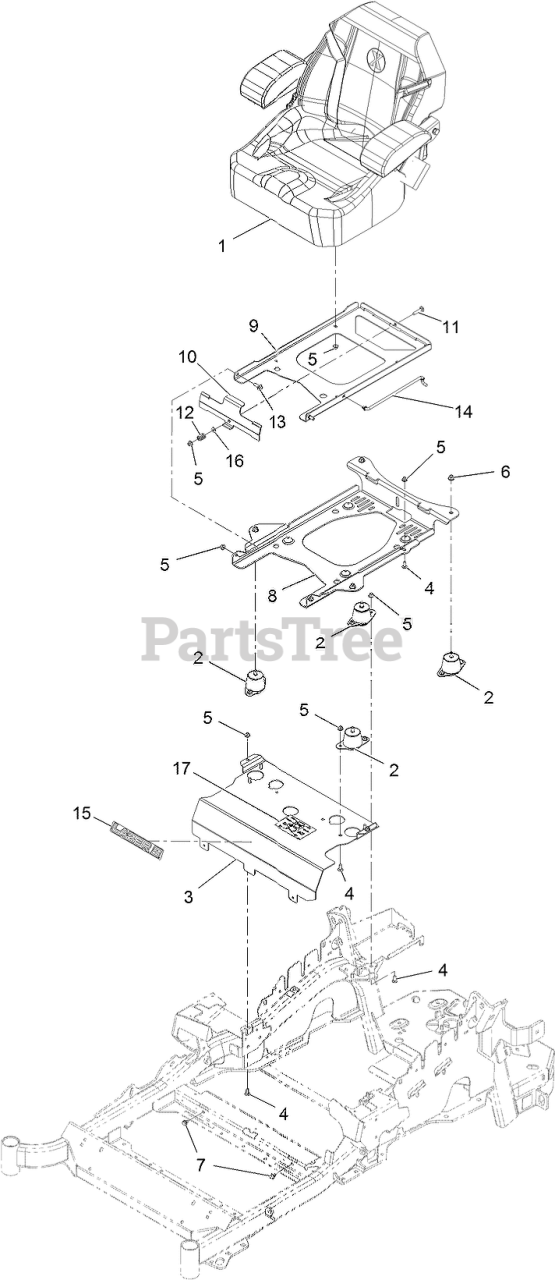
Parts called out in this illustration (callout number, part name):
1	SEAT-EXMARK STANDARD
2	ISOLATOR-SEAT
3	Panel,Seat Mount-Front
4	SCREW-CARR
5	NUT-HF, NI
6	NUT-HF, NI
8	PLATE-TILT, SEAT SUPPORT
9	PLATE-FRAME, SEAT
10	PLATE-LATCH, SEAT
11	BOLT-CARR
12	SPRING-COMPRESSION
13	SCREW-SHOULDER
14	ROD-PROP
15	DECAL, LAZER MODEL
16	WASHER-PLAIN
17	DECAL-SERVICE AID
